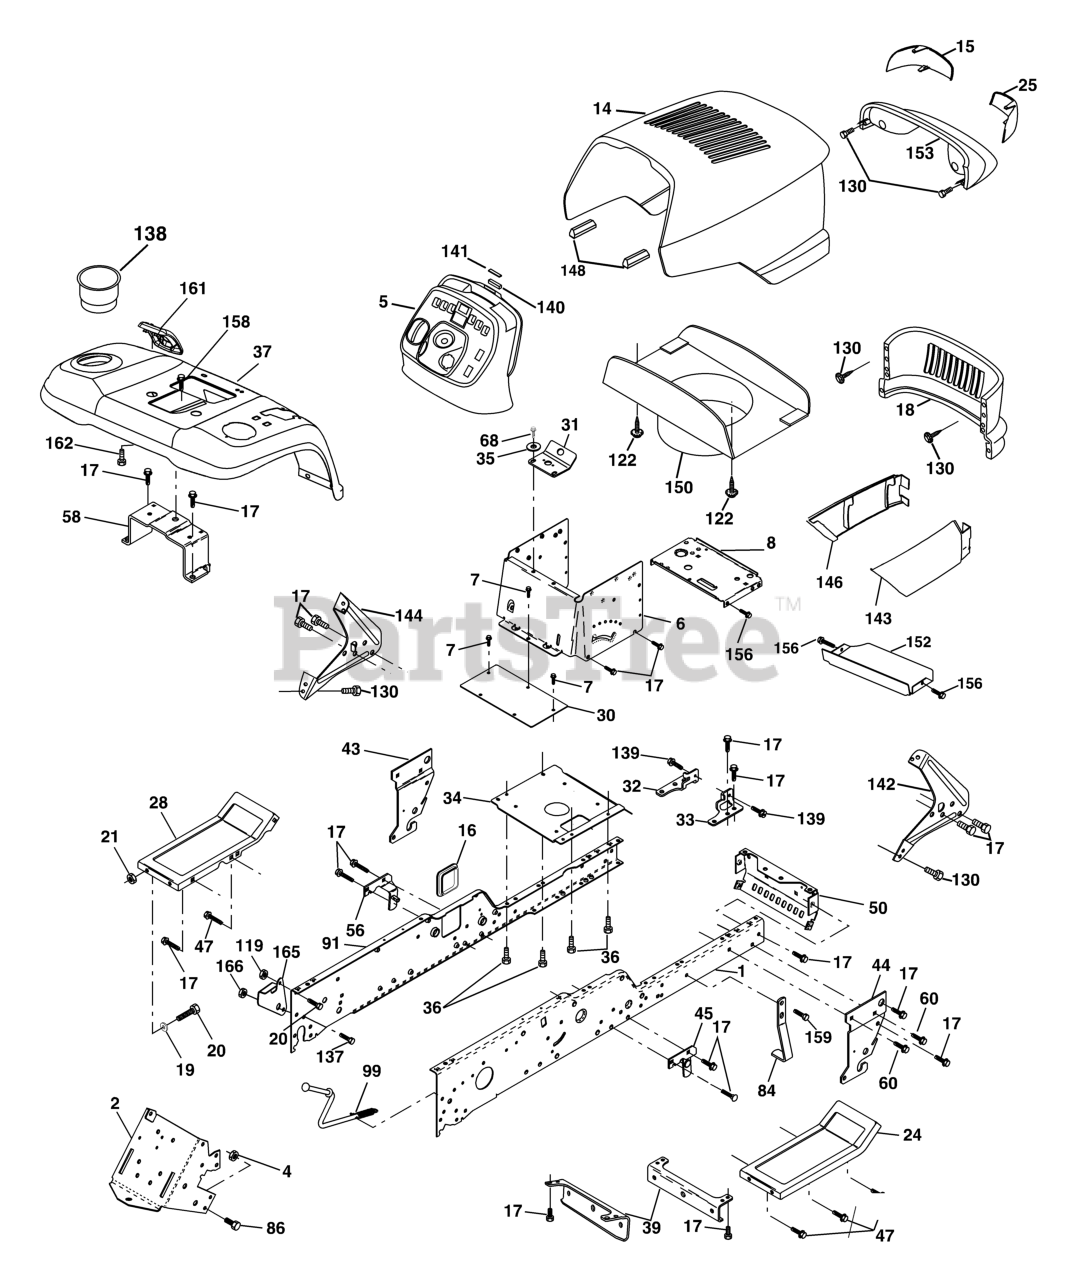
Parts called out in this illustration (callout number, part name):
1	FRAME RAIL RH
2	DRAWBAR, GT
4	Nut, Lock Hex 7/16 Unc
5	DASH.STEALTH.YTGT.2CYL.BLK
6	DASH VGT, LOWER
7	SCREW
8	SUPPORT, BATTERY
14	HOOD ASM.
15	LENS LH
16	COVER ACCESS
17	SCREW 3/8-16X3/4
18	GRILLE
19	WASHER
20	BOLT
24	FOOTREST PNT RH
25	LENS RH
28	FOOTREST PNT LH
30	SADDLE.HYDRO.95
31	BRACKET SUPT 1-PC VGT STEERING
34	PLATE ASM ENG CHASSIS
35	WASHER
36	SCREW 5/16"
37	FENDER, PNT
39	BRACKET AXLE, FRONT
43	FRONT SUSPENSION BRKT LH
44	FRONT SUSPENSION BRKT RH
45	BRACKET SUSP RH
47	SCREW LT
50	BRACKET, CHASSIS FRONT
56	BRACKET ASM, SUSP CHASSIS
58	BRACKET ASM, FENDER
60	SCREW.3/8-16
68	Screw, 5/16-18 x 1/2
84	MOWER STOP
86	BOLT
91	FRAME RAIL LH
99	ROD ASM, BYPASS
122	SCREW.HEX.WS.HD.8-18 X 7/8
130	SCREW
137	BOLT FIN HEX 7/16-14 X 1
138	CUPHOLDER
139	BOLT, SHOULDER 5/16-18
140	MAGNET STEALTH
141	STRIKER PLATE
142	BRACKET DASH STEALTH(R)
143	SKIRT GRILLE RH
144	BRACKET DASH STEALTH LH
146	SKIRT GRILLE LH
148	EXTRUSION BUMPER (3 2) (2 2)
150	DUCT HEAT HOOD
152	BROWNING SHIELD
153	LIGHT ASM.
156	SCREW
158	SCREW 3/8-16X1/2
159	SCREW, 3/8-16X3/4
161	CONSOL.FUEL.WINDOW.BLACK
162	SCREW.HI-LO.CONSOLE
165	Bracket Support Fuel Tank
166	Nut Crownlock 7/16-14
